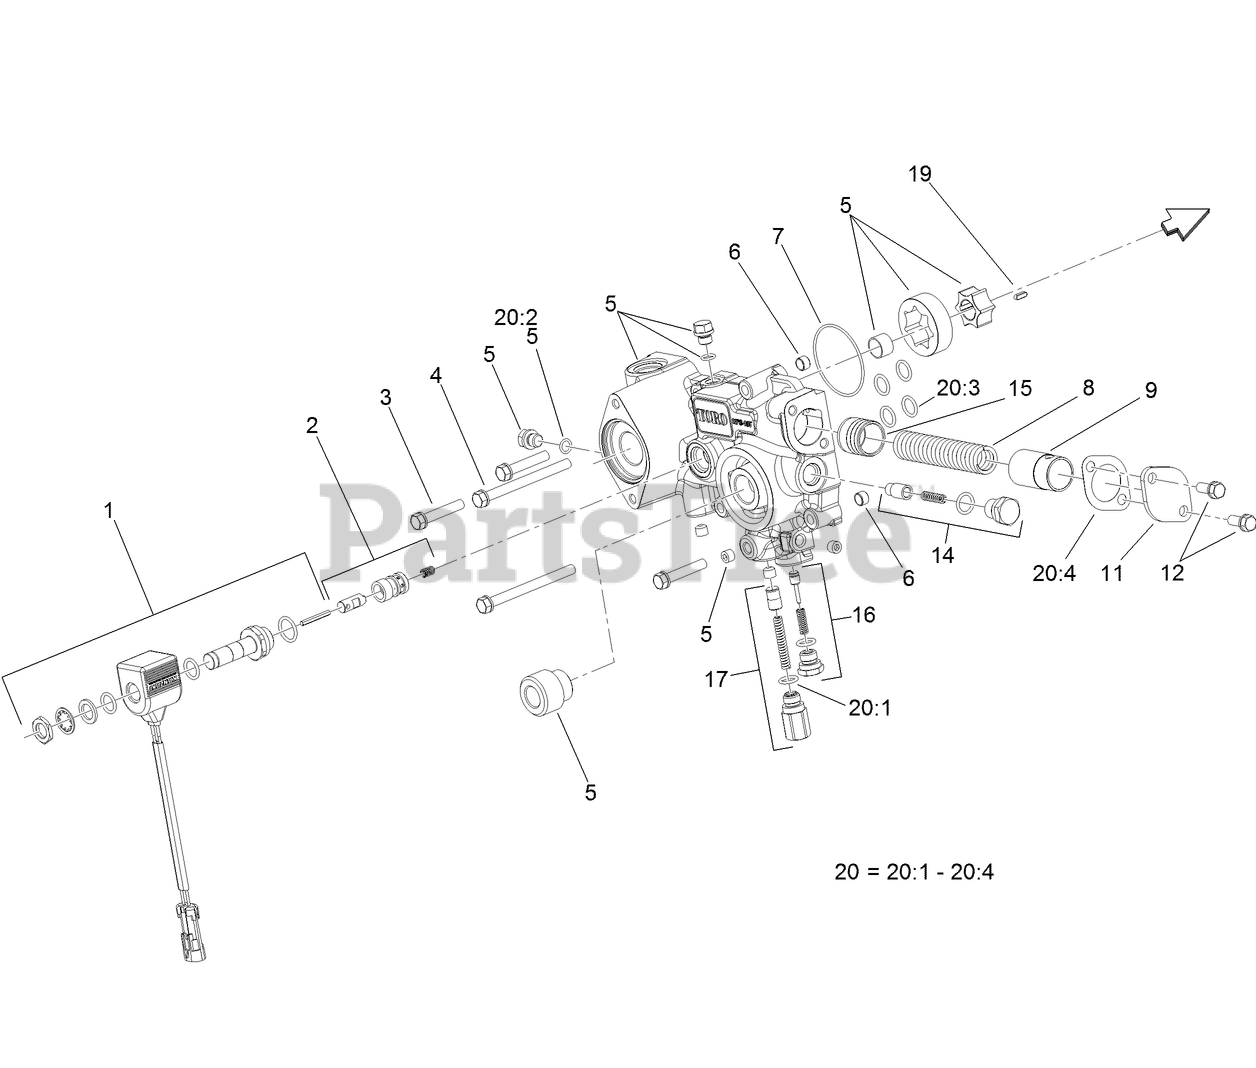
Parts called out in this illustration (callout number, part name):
1	SOLENOID ASM
2	SOLENOID VALVE ASM
5	PUMP BODY ASM
7	O-RING
8	SPRING
9	COLLAR
12	BOLT AND WASHER ASM
14	FILTER BYPASS VALVE ASM
15	PISTON
16	CHARGE RELIEF VALVE ASM
17	PRESSURE VALVE ASM
20	CHARGE PUMP SEAL KIT
20:1	O-RING
20:2	O RING-PLUG
20:4	GASKET
